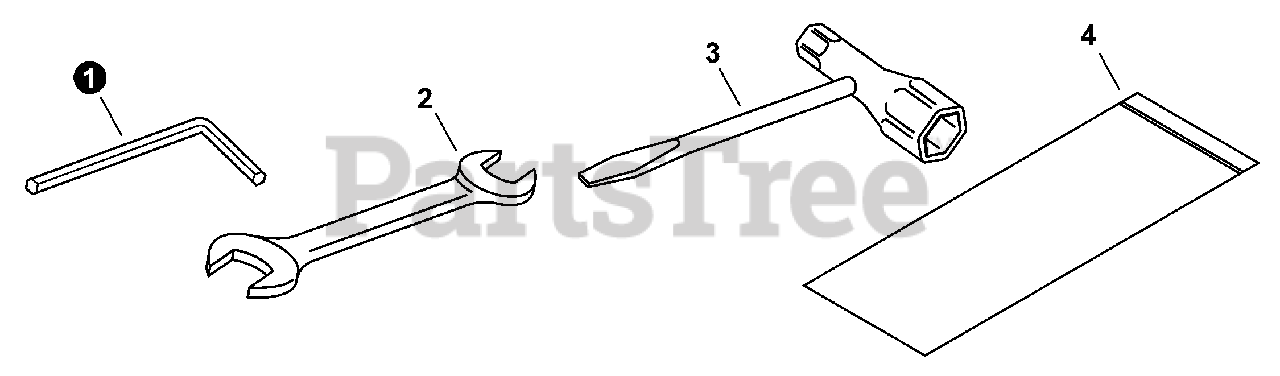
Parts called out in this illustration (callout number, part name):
1	WRENCH, ALLEN 3 MM
2	SPANNER 8×10
3	T-WRENCH 16×13
4	BAG, TOOL
